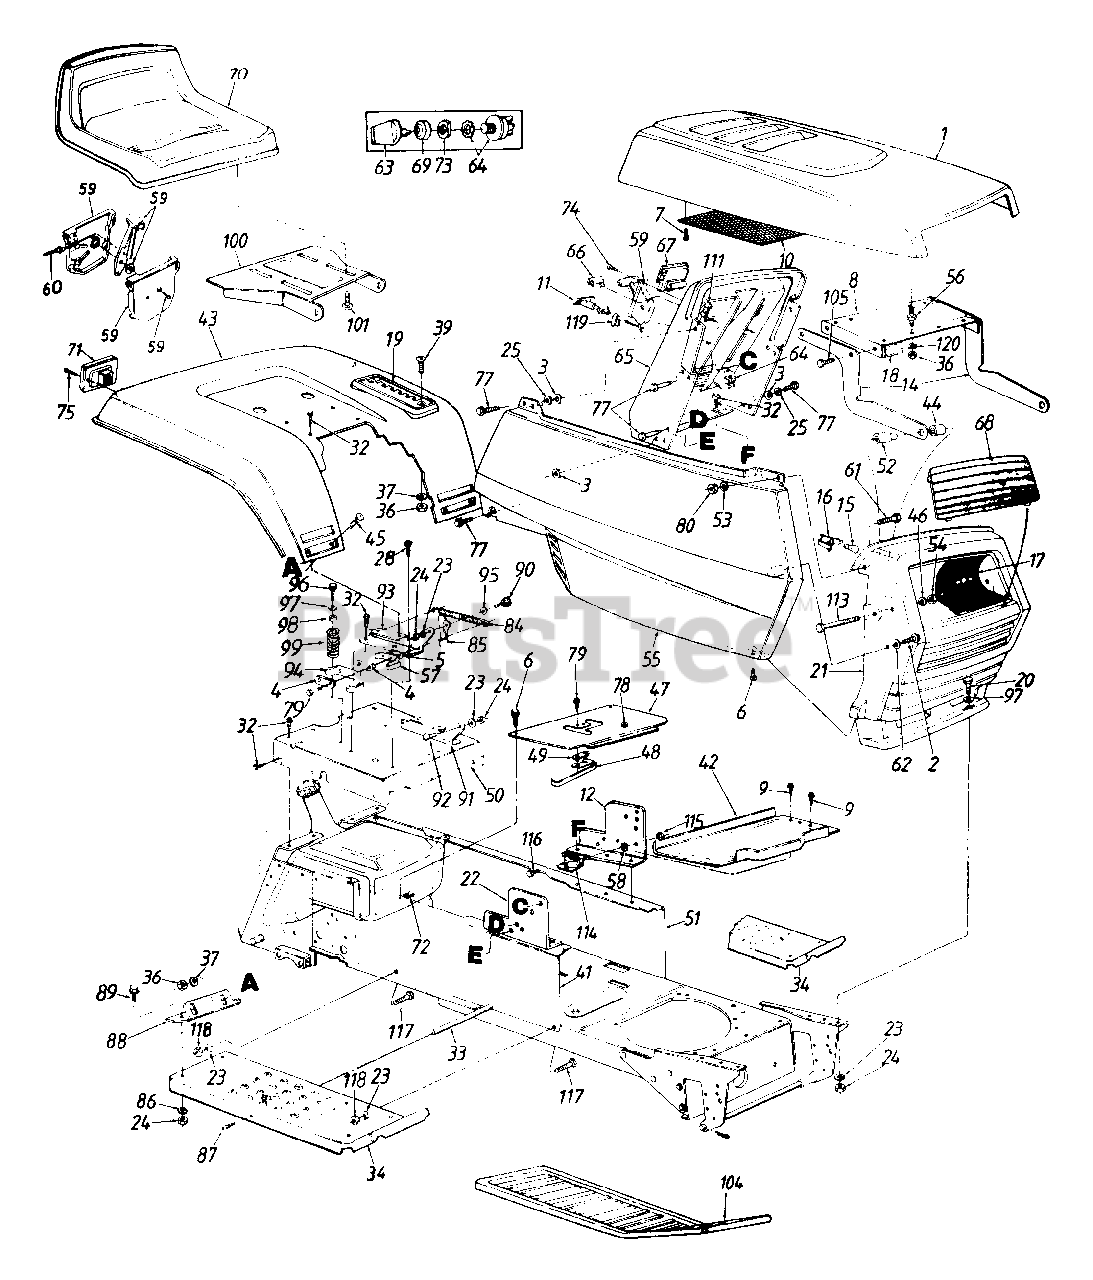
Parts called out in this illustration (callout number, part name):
1	Hood
2	Hex Wash. B-Tap Scr. 1/4 x .62" Lg.
3	Bolt Retainer 1/4" I.D.
4	Insulator Plate
5	Insulator Boss Plate
6	Truss Mach. B-Tap Scr. #10 x .5" Lg.
7	Hex Wash Hd. AB-Tap Scr. #8 x .5" Lg.
8	Hood Plate
9	Hex AB-Tap Scr. 1/4 x .62" Lg.
11	Choke Control
12	Dash Support Brkt. - L.H.
14	Hood Hinge
15	Lamp
16	Twist Lock - Lamp Socket
17	Reflector - Headlight
19	Speed Control Index Brkt.
20	Hex Bolt 5/16-18 x .75" Lg.
21	Grille
22	Dash Support Bracket - R.H.
23	L-Wash. 5/16" I.D.
24	Hex Nut 5/16-18 Thd.
25	Fl-Wash. 1/4" I.D. x .93" O.D.
28	Torx AB-Tap Scr. 5/16-18 x .75" Lg.
32	Hex Wash. Hd. AB-Tap Scr. 5/16 x .75" Lg.
33	Running Board Rod
37	L-Wash. 1/4" I.D.
39	Truss Mach. Scr. 1/4-20 x .62"
41	R.H. Side Frame
42	Support Brkt.
45	Carriage Bolt 1/4-20 x .50" Lg.
46	Fl-Wash. .328" I.D. x .68" O.D.
47	Transmission Panel
48	Reverse Safety Switch
49	Insulator Nut Plate
52	Shld. Spacer .33" I.D.
53	Fl-Wash. .281" I.D. x .5" O.D.
54	Hex Cent. L-Nut 5/16-18 Thd.
55	Side Cover Ass'y. - R.H.
56	Double Ended Stud 1/4-20 Thd.
57	Safety Switch (Seat)
58	Ext. L-Wash. 1/4" I.D.
59	Throttle Control Box Ass'y.
60	Throttle Control Wire 35" Lg.
61	Hex Bolt 1/4-20 x .62" Lg.
62	Fl-Wash. .281" I.D. x .73" O.D.
64	Ignition Switch
66	Light Switch
67	Ammeter
68	Lens
69	Ignition Switch Cap
71	Taillight Assy.
72	Speed Nut #10Z
73	Ignition Switch Nut
74	Truss Mach. RB-Tap Scr #10 x .5" Lg.
75	Truss Hd. AB-Tap Scr. #6 x .62" Lg.
77	Hex Wash. Hd. Tap Scr. 1/4 x .75" Lg.
78	Snap Bushing
79	Hex Wash. Hd. AB-Tap Scr. #8 x .50" Lg.
80	Hex L-Nut 1/4-20 Thd.
84	Ext. Spring 5.31" Lg.
85	Seat Lift Brkt.
86	Bell-Wash. 345" I.D. x .88" O.D.
87	Rib Neck Bolt 5/16-18 x .75"
90	Shld. Bolt .437" Dia. x .268"
95	Spr.-Wash. .445" I.D.
96	Hex Wash. Hd. Tap Scr. 5/16-18 x 1" Lg.
97	Fl-Wash .344" I.D. x 1" O.D.
99	Compression Spring
100	Seat Pivot Bracket
101	Hex Tap Scr 3/8-16 x 75"
105	Hex Tap Scr. 1/4-20 x 5" Lg.
111	Speed Nut 1/4-20 Thd.
113	Hex Bolt 5/16-18 x 2.75"
114	Solenoid
115	Hex Sems Nut 1/4-20 Thd
116	Hex Bolt 1/4-20 x .5" Lg.
117	Rib Neck Bolt 5/16-24 x .75" Lg.
118	Hex Nut 5/16-24 Thd.
119	Retainer Clip
120	Bell-Wash. .265" I.D x .75" O.D.
